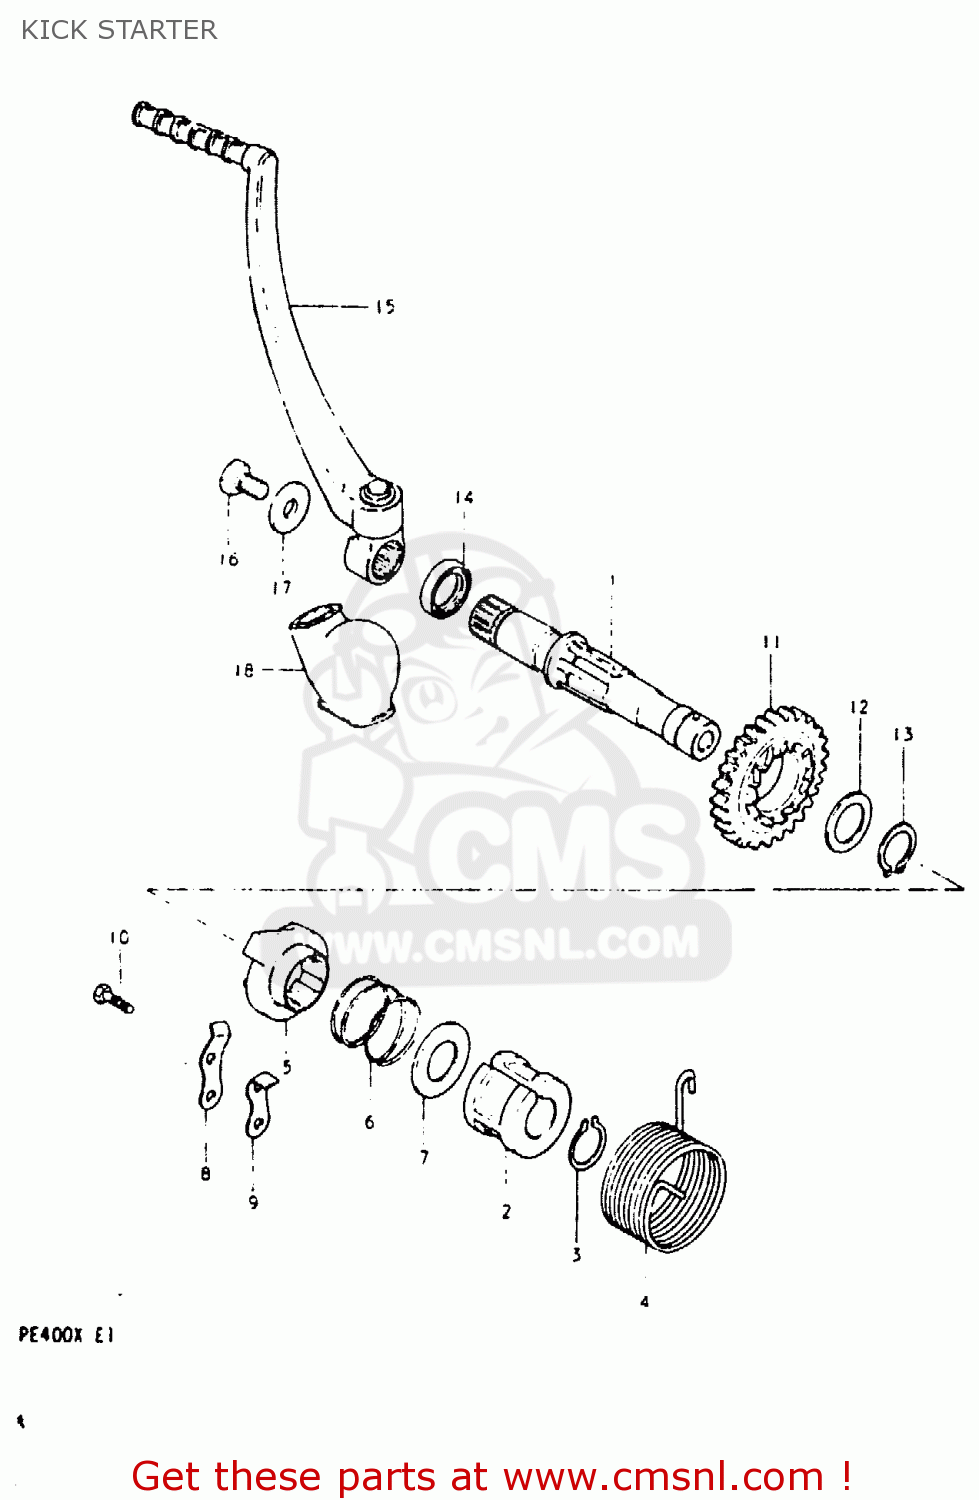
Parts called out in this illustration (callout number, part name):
1	SHAFT,KICK STARTER
2	GUIDE,KICK STARTER SFT SPRING
3	CIRCLIP
4	SPRING
5	STARTER,KICK
6	SPRING
7	WASHER
8	GUIDE,KICK STARTER
9	STOPPER,KICK STARTER
10	BOLT(8X20)
11	GEAR,KICK STARTER DRIVE
12	SHIM
13	CIRCLIP
14	SEAL,OIL(20X27X5)
15	LEVER ASSEMBLY,KICK STARTER
16	BOLT
17	WASHER(8.2X23X3.2)
18	COVER,KICK LEVER JOINT
